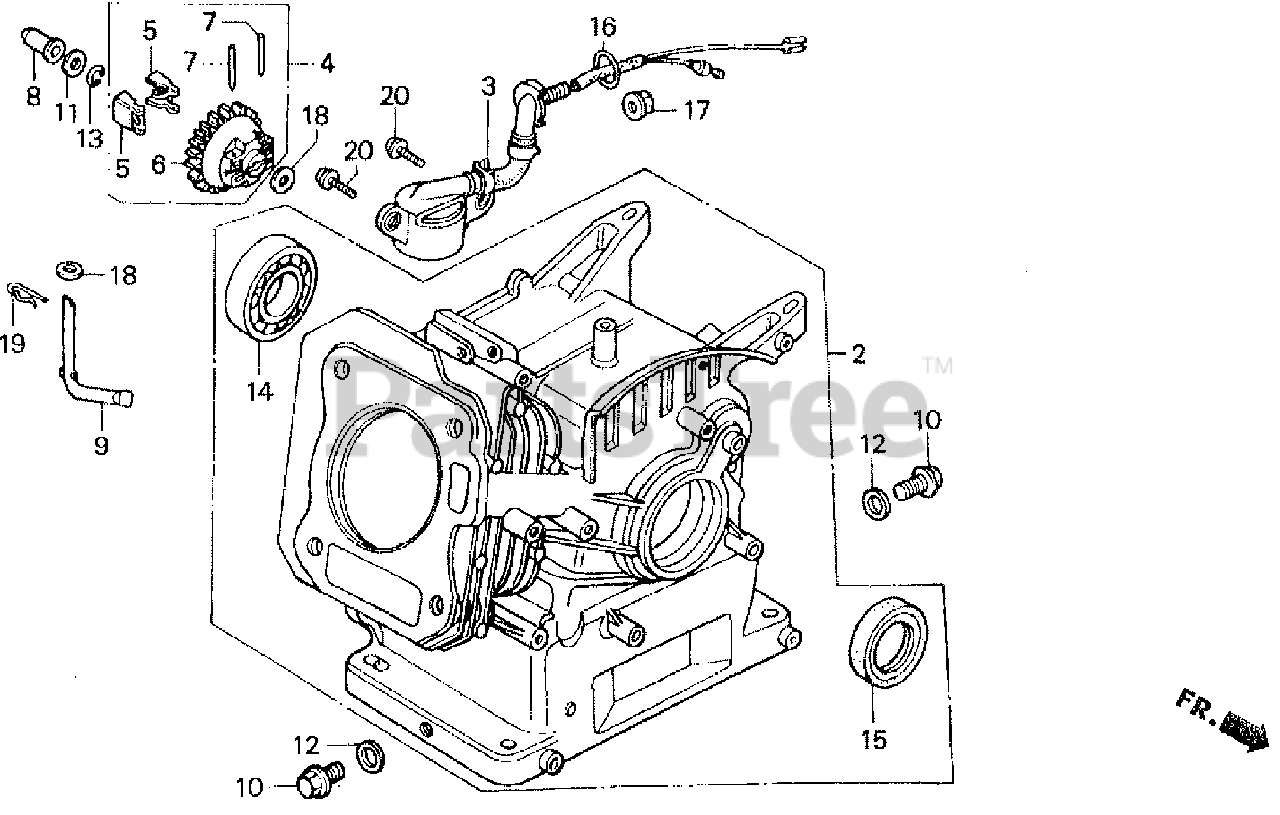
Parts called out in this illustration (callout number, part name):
2	CYLINDER ASSY. (OIL ALERT)
3	SWITCH ASSY., OIL LEVEL
4	GOVERNOR ASSY.
5	WEIGHT, GOVERNOR
6	HOLDER, GOVERNOR WEIGHT
7	PIN, GOVERNOR WEIGHT
8	SLIDER, GOVERNOR
9	SHAFT, GOVERNOR ARM
10	BOLT, DRAIN PLUG
11	WASHER, THRUST (6MM)
12	WASHER, DRAIN PLUG (10.2MM)
13	CLIP, GOVERNOR HOLDER
14	BEARING, RADIAL BALL (6205)
15	OIL SEAL (25X41X6)
16	O-RING (13.5X1.5) (ARAI)
17	NUT, FLANGE (10MM)
18	WASHER, PLAIN (6MM)
19	PIN, LOCK (8MM)
20	BOLT, FLANGE (6X12)
